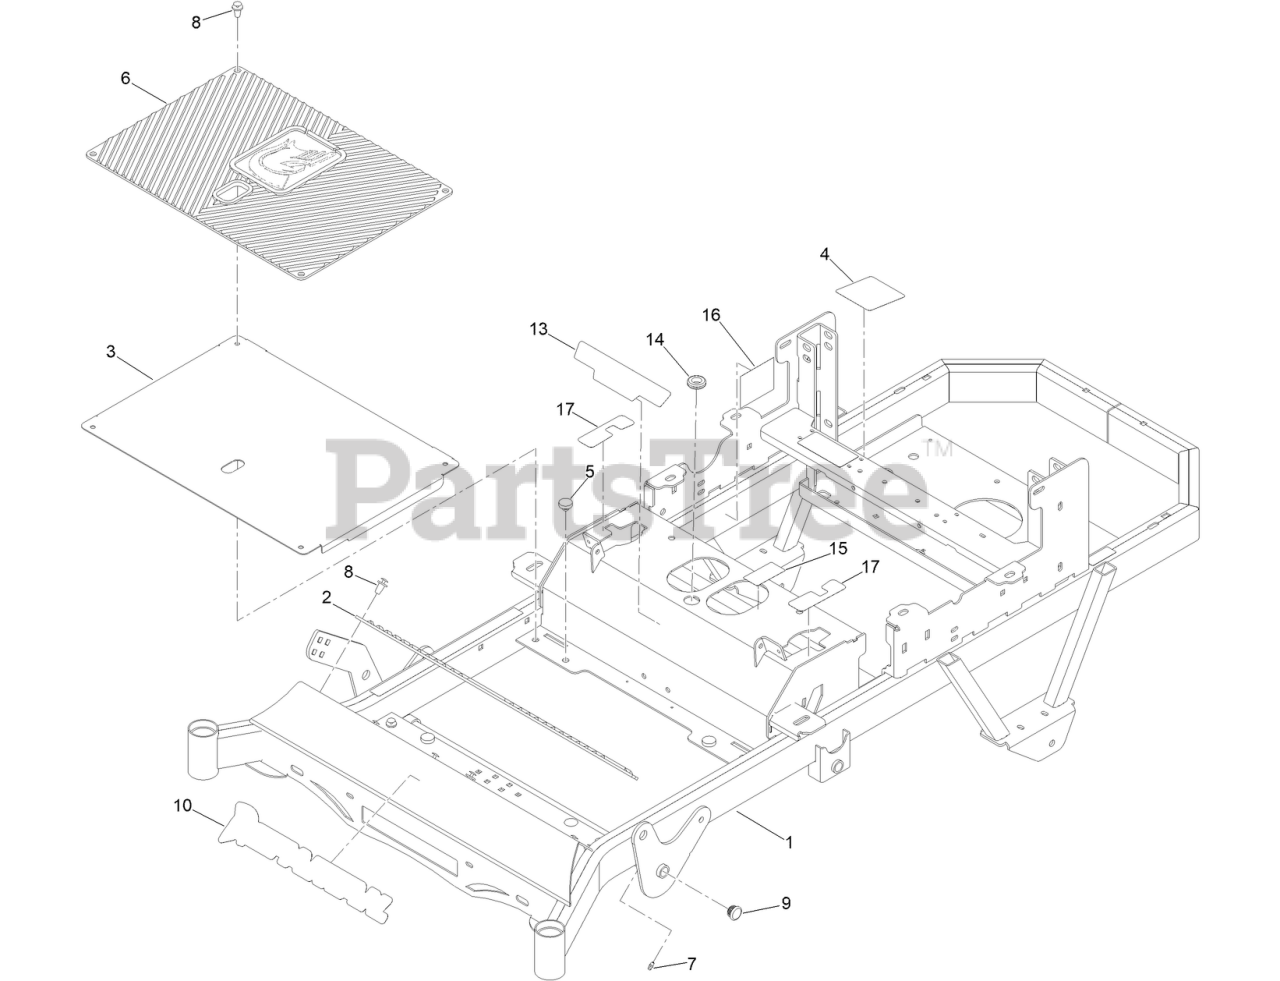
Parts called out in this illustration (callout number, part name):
1	FRAME ASM W/ DECALS
2	MWR RUBBER FOOT REST MAT
3	RZ FLOORBOARD PAINTED
4	DECAL-PUMP BELT ROUTING-TUFF TORQ
5	PUSH-IN RUBBER BUMPER MWR FLOOR
6	MWR LOGO FLOOR MAT
7	1/4 DRIVE TYPE STRAIGHT GREASE FITTNG ZC
8	8MM PUSH TYPE RETAINER NYLON BLACK
9	1IN ROUND TUBE PLUG
10	MWR FT SPARTAN LOGO
13	DECAL- RZ PRO GT TRAC MODEL
14	GROMMET-RUBBER
15	MWR SEAT WEIGHT CAPACITY DECAL
16	DECAL-E P A
17	SPARTAN DRIVE ARM F/N/R DECAL
